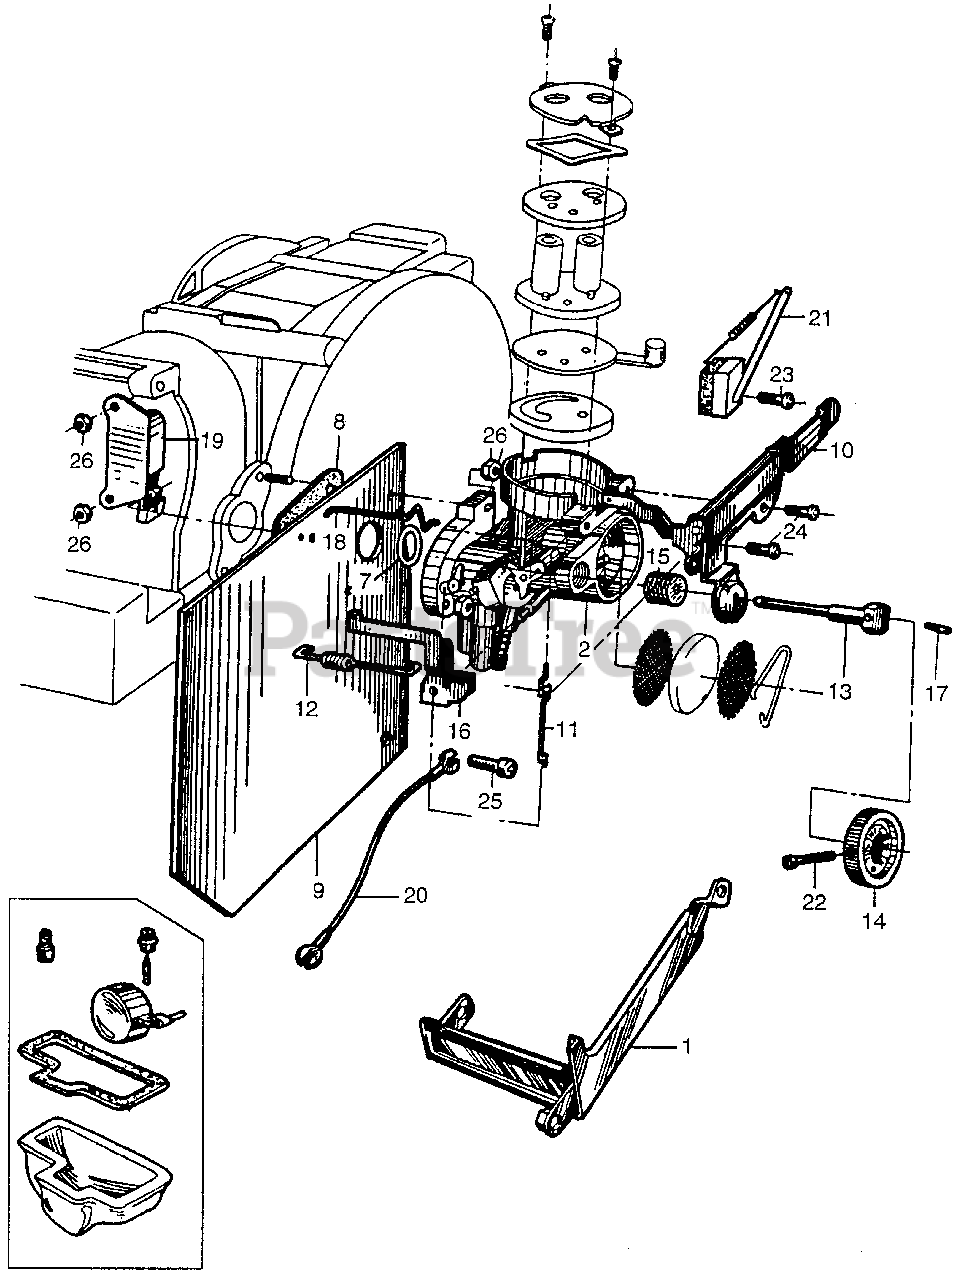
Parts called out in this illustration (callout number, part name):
1	PLATE, GUIDE
2	CARBURETOR ASSY. (NOT AVAILABLE)
3	FLOAT SET (NOT AVAILABLE)
4	VALVE, FLOAT (NOT AVAILABLE)
5	JET, MAIN (NOT AVAILABLE)
6	WASHER, CHAMBER (NOT AVAILABLE)
7	O-RING (NOT AVAILABLE)
8	GASKET, CARBURETOR (NOT AVAILABLE)
9	INSULATOR, CARBURETOR (NOT AVAILABLE)
10	SHAFT, ARM
11	ROD, GOVERNOR (NOT AVAILABLE)
12	SPRING, GOVERNOR (NOT AVAILABLE)
13	SHAFT, GOVERNOR (NOT AVAILABLE)
14	GOVERNOR (OUTER) (NOT AVAILABLE)
15	SCREW, GOVERNOR CONTROL (NOT AVAILABLE)
16	LEVER, GOVERNOR SPRING (NOT AVAILABLE)
17	ADJUSTER, GOVERNOR (NOT AVAILABLE)
18	ROD, CHOKE LEVER (NOT AVAILABLE)
19	CHOKE, AUTO (NOT AVAILABLE)
20	WIRE, GROUND (NOT AVAILABLE)
21	SWITCH, ENGINE (NOT AVAILABLE)
22	SCREW, STOP (3MM) (NOT AVAILABLE)
23	SCREW, PAN (3X6) (NOT AVAILABLE)
24	SCREW, PAN (4X6)
25	SCREW, PAN (5X6)
26	NUT, HEX. (5MM)
